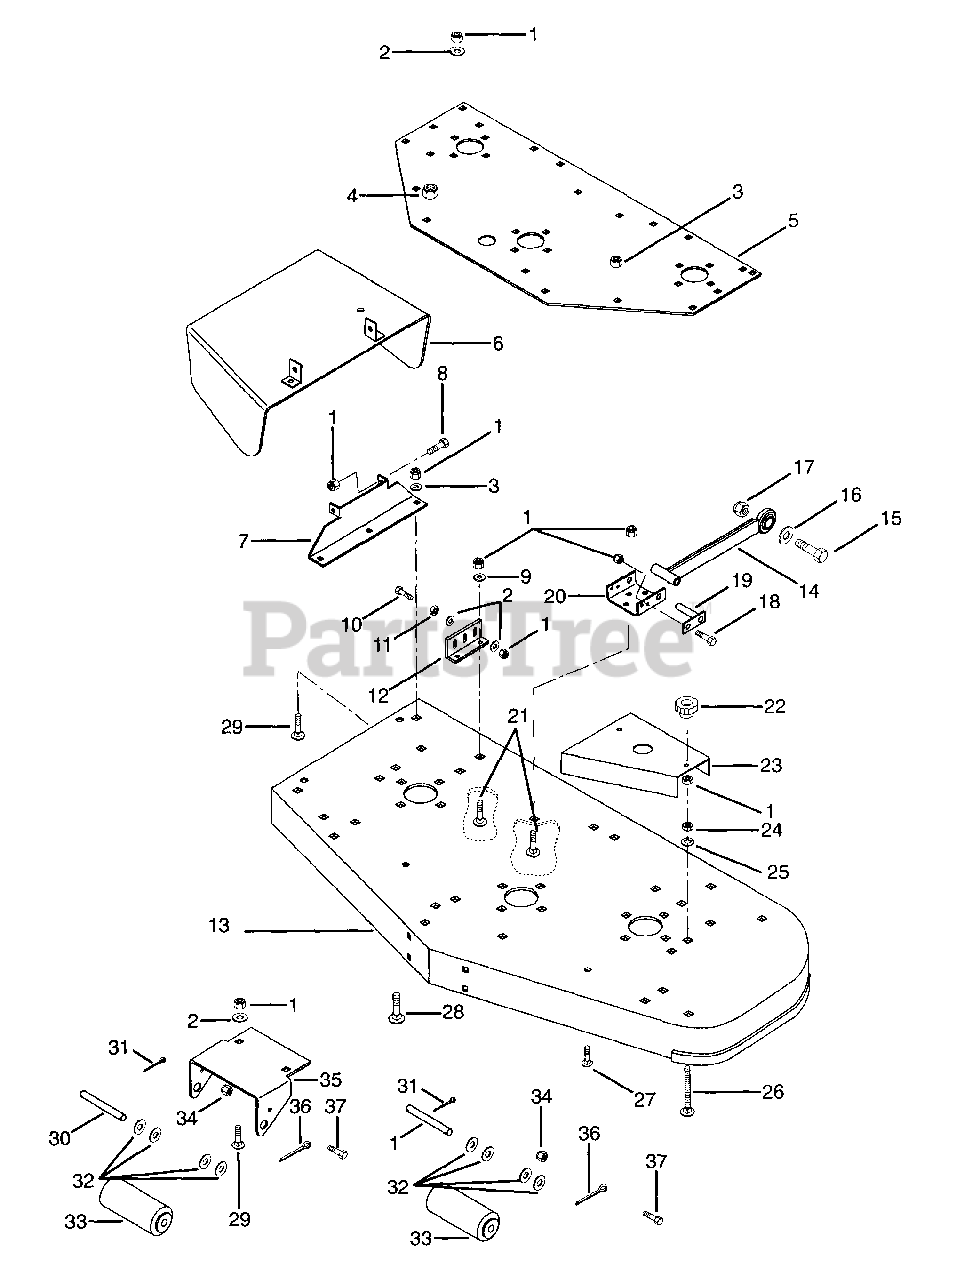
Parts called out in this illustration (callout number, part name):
1	Nut-Locking-Center .375-16
2	Washer-Flat-Steel .406 x .812 x .065
3	Nut-Locking-Center .31-18
4	Nut-Locking-Center .50-13 Grade 2
5	Plate-60" Support
6	Weldment-Discharge Chute
7	Bracket-Discharge
8	Bolt-Hex .38-16 x 1.00 Grade 5
9	Bushing .406 x .750 x .188
10	Bolt-Hex .38-16 x 1.50 Grade 5
11	Nut-Locking-Center .38-16
12	Bracket-Mower Mounting (60" Mower)
13	Weldment-Deck 60" Mower PM200
14	Weldment-Mower Mounting Arm
15	Bolt-Hex .875-9 x 2.75 Grade 5
16	Washer-Flat-Steel .875 x 1.500 x .1196
17	Nut-Locking-Center .875-9
18	Bolt-Hex .38-16 x .75 Grade 5
19	Weldment-Mower Mounting Pin
20	Bracket-Mower Mounting (Rear)
21	Bolt-Round Head Square Neck .38-16 x 1.25 Grade 2
22	Knob
23	Guard-Pulley L.H. 60" Mower
23	Guard-Pulley R.H. 60" Mower
24	Nut-Locking-Center .31-18 Grade 2
25	Washer-Locking .31 x .078
26	Bolt-Round Head Square Neck .31-18 x 3.50 Grade 5
27	Bolt-Round Head Square Neck .31-18 x .75 Grade 5
28	Bolt-Round Head Square Neck .50-13 x 1.00 Grade 2
29	Bolt-Round Head Square Neck .38-16 x 1.0 Grade 2
30	Shift-Center Roller
31	Pin-Center .25 x 1.00
32	Washer-Flat-Steel .656 x 1.312 x .095
33	Roller-Gage
34	Nut-Locking-Nylon .250-20 Grade 2
35	Bracket-Roller R.H.
36	Pin-Cotter .250 x 2.00
37	Bolt-Hex .25-20 x .75 Grade 5
